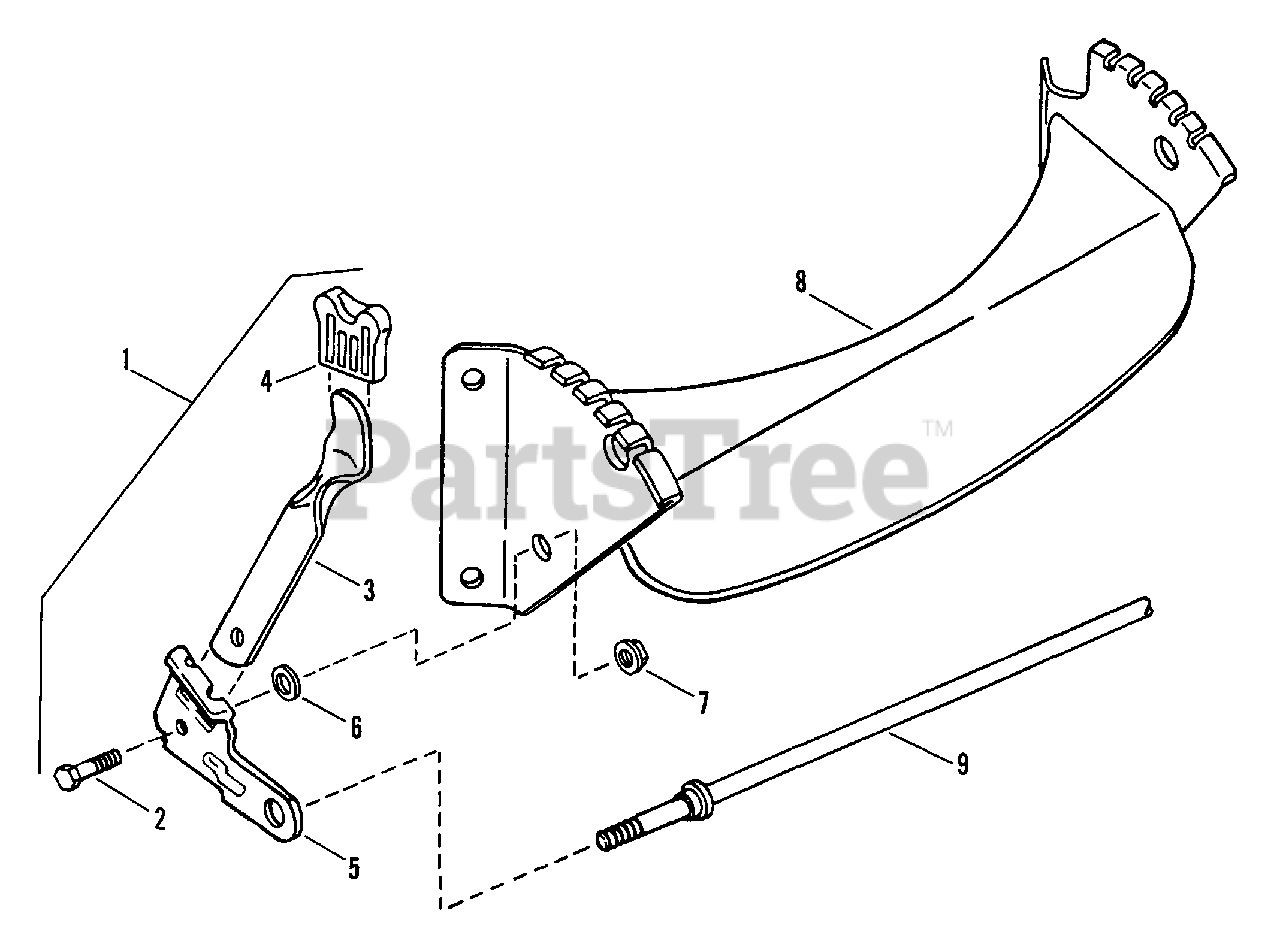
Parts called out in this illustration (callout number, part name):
1	ASSEMBLY, Arm, Left Wheel
2	BOLT, 5/16-18 x 3/4" Shoulder
3	LATCH, Height
4	GRIP, Latch
5	ARM, Left Wheel
6	RETAINER, 5/16 Bolt
7	NUT, 5/16-18 Hex Flange Lock
8	BRACKET, Front Wheel
9	AXLE
